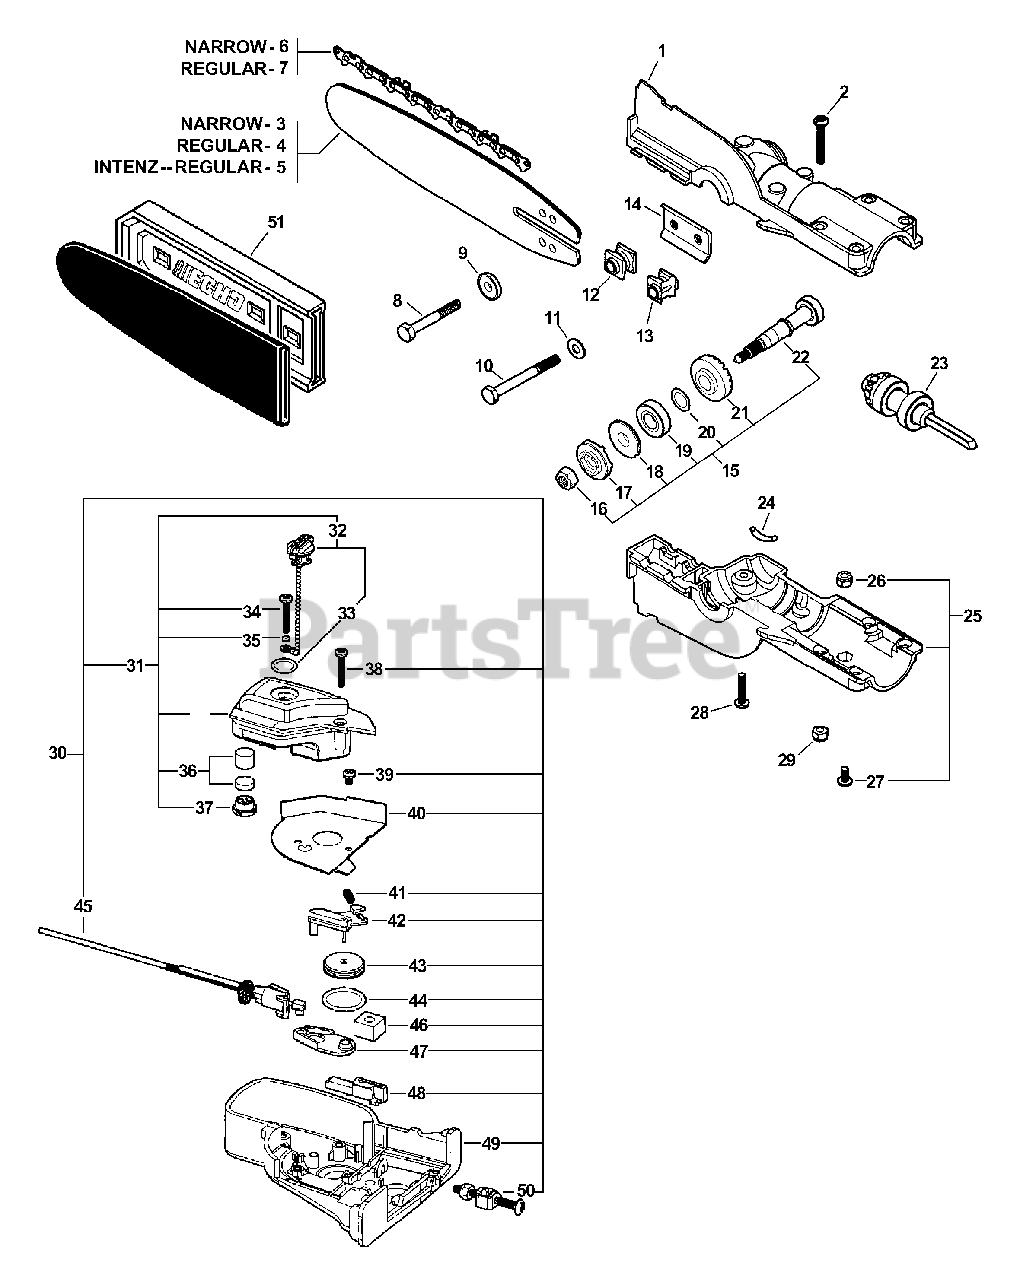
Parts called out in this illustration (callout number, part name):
1	CASE, GEAR
2	SCREW, TORX 10-24 UNC 1-1/4
3	GUIDE BAR - 12"
4	GUIDE BAR - 12"
5	GUIDE BAR - 12" -- INTENZ
6	SAWING CHAIN - 90SG - 12" -- MICRO-LITE
7	SAWING CHAIN - 91VS - 12" -- LOW PROFILE
8	SCREW
9	WASHER 6
11	WASHER, FLAT
12	SPACER
15	GEAR SHAFT ASSY
16	NUT, HEX
17	SPROCKET, DRIVE
18	SPACER, SPROCKET
19	BEARING, BALL 6001 DDU
20	WASHER 12
21	GEAR, BEVEL
22	SHAFT, GEAR
23	SHAFT GEAR ASSY
25	CASE, GEAR
26	NUT, LOCK 10-24 UNC
27	SCREW
28	SCREW, TORX
29	NUT, LOCK 10-24 UNC
30	AUTO-OILER ASSY
31	OIL TANK ASSY
32	CAP, OIL
34	SCREW, TORX
36	FILTER, OIL
37	GROMMET, OIL
38	SCREW, TORX
39	SCREW 8-32×1/4
40	PLATE, PROTECTION
41	SPRING, COMPRESSION
42	LINK, OILER IDLER
43	CAM, OIL PUMP
45	AUTO-OILER ASSY
46	SPACER
47	LINK, OILER DRIVE
49	COVER, OILER
50	TENSIONER ASSY, CHAIN
51	SCABBARD
